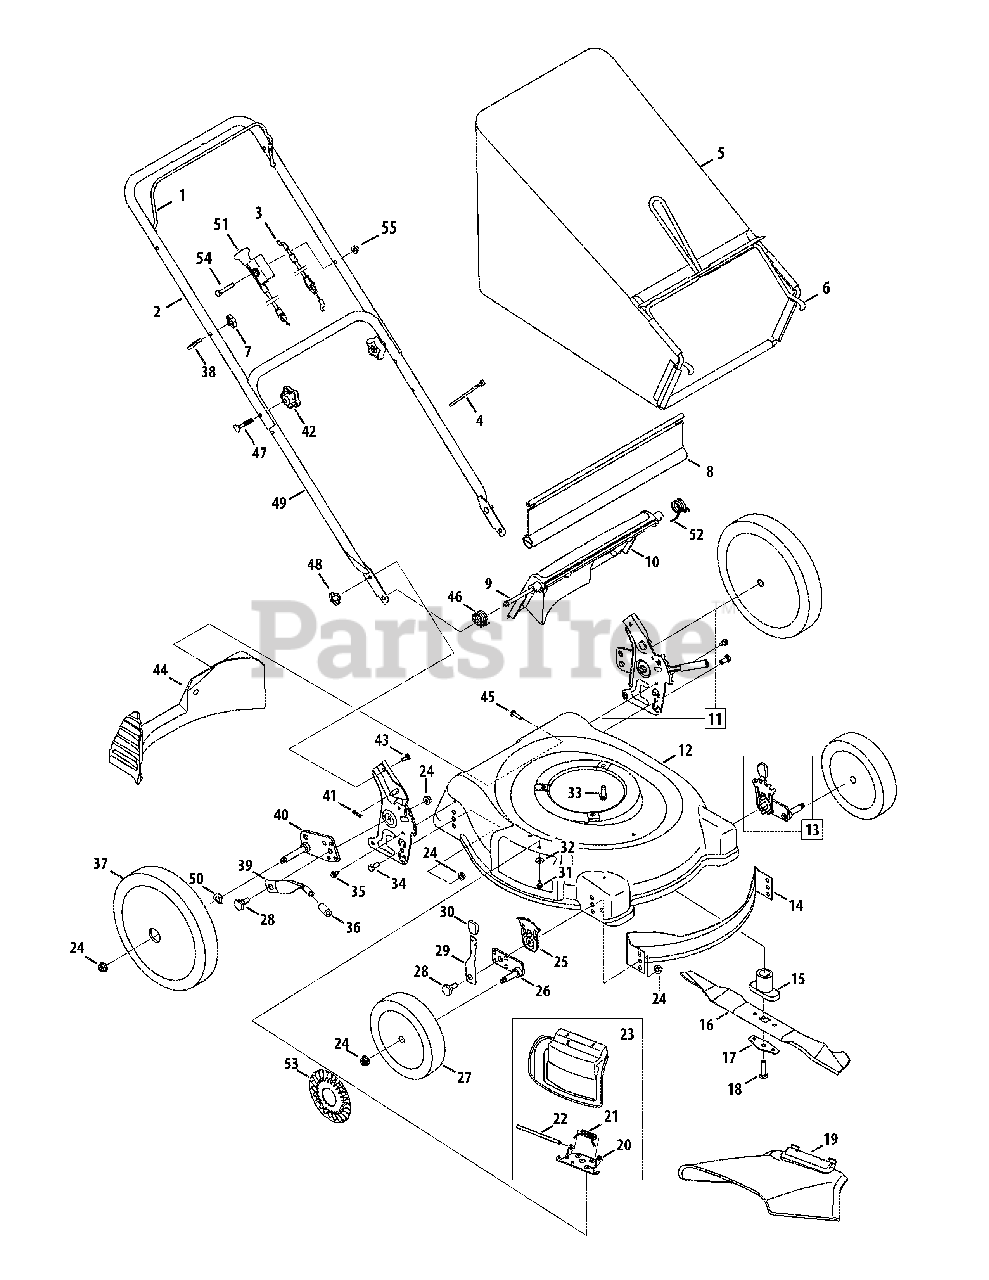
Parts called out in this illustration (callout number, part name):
3	Control Cable
4	Cable Tie
5	Grass Bag Assembly
8	Trailshield
10	Rear Discharge Door
11	Rear Handle Bracket Assy. - LH
11	Rear Handle Bracket Assy. - RH
13	Front Hgt. Adj. Assy. - RH
14	Front Baffle
15	Blade Adapter
16	21-inch Mulching Blade
17	Bell Blade Support
18	Hex Screw, 3/8-24 x 2.5
19	Side Discharge Chute
20	Deflector Chute Adaptor
21	Torsion Spring
22	Hinge Pin
23	Mulch Plug Assembly
24	Flange Lock Nut 3/8-16
25	Height Adjustment Plate
26	Pivot Arm Assy RH
26	Pivot Arm Assy LH
27	Front Wheel
28	Shoulder Scr., .5D x .385
29	Front Spring Lever
30	Height Adjust Knob
31	TT Screw, 1/4-20 x .500
33	TT Screw, 3/8-16 x 1.0
34	Hex Screw, 3/8-16 x .75
35	TT Screw, 1/4-20 x .625
37	Rear Wheel, 12 x 2.125, Zag
39	Rear Hi-Wheel Spring Lever
40	Rear Pivot Arm Assy - RH
40	Rear Pivot Arm Assy - LH
41	Hairpin Clip
42	Star Knob
43	Carriage Bolt ,1/4-20 x .75
45	Screw HL, 1/4-15 x 1.00
46	Torsion Spring - RH
47	Carriage Bolt, 5/16-18 x 2
48	Wing Nut
50	Spring Washer
52	Torsion Spring - LH
53	Hub Cap
54	Screw, 1/4-20 x 1.50
55	Nut, Flange Lock, 1/4-20
